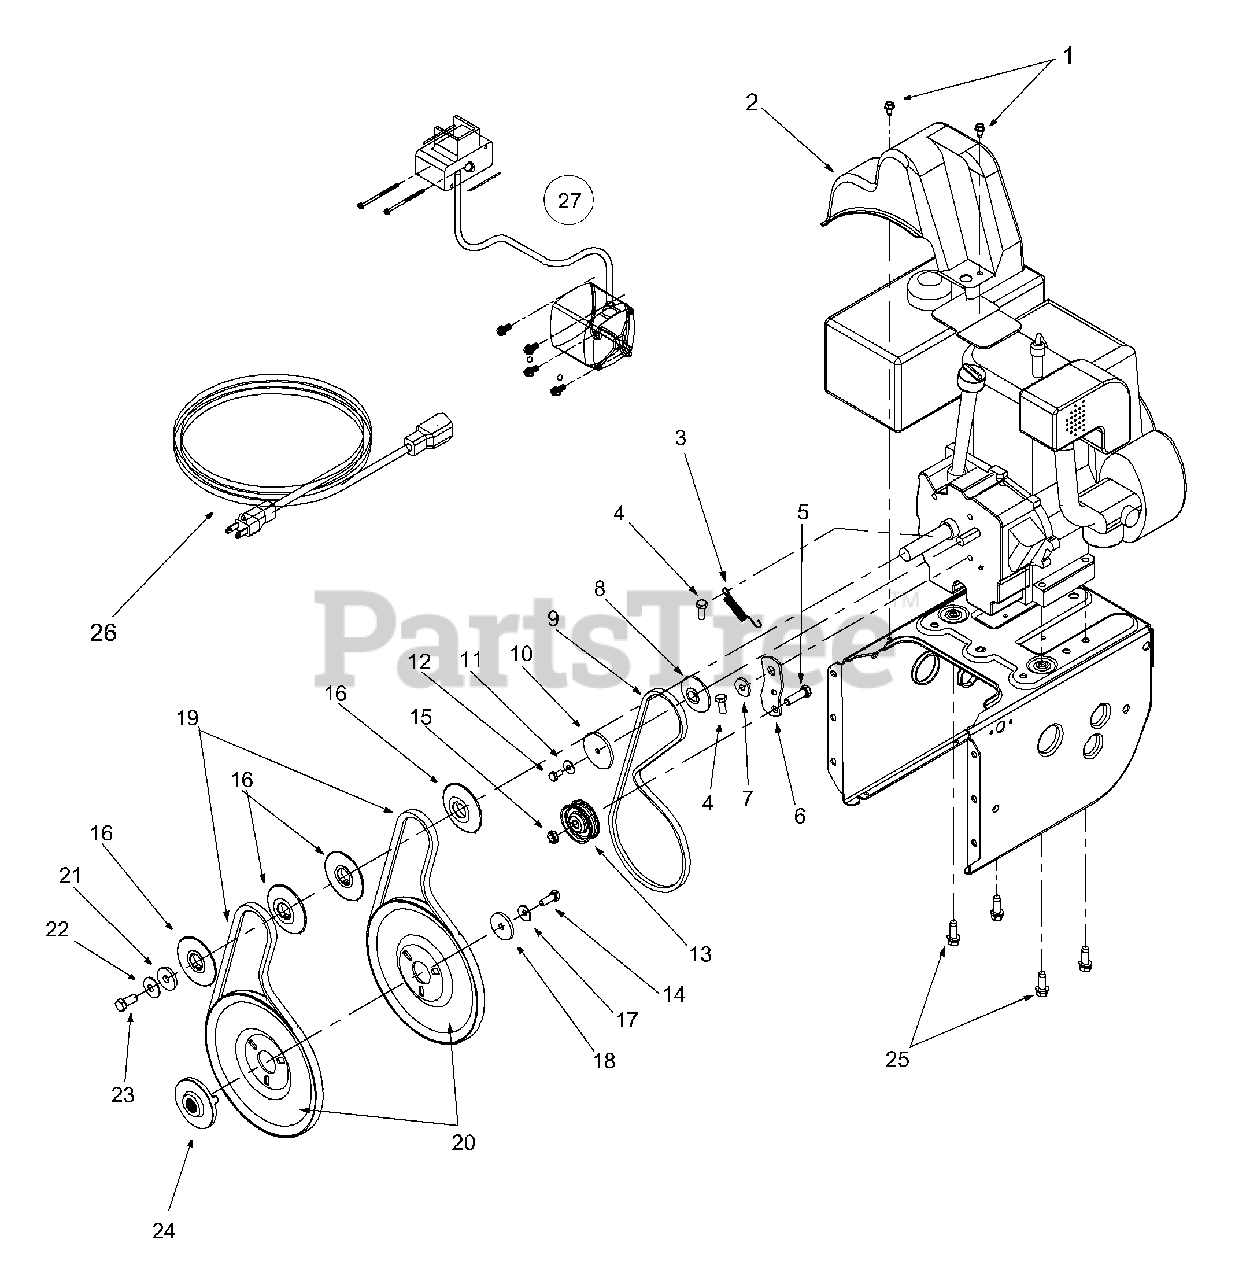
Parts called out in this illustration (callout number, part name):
1	Hex Washer Screw 1/4-20 x .50
2	Belt Cover
3	Extension Spring
4	Hex Screw 5/16-24 x .75
5	Hex Cap Screw 3/8-16 x 1.25
8	Pulley Half
9	V-Belt
10	Pulley Half
11	Bell Washer
12	Hex Cap Screw 1/4-28 x .50
13	Flat Idler
14	Lock Hex Cap Screw 5/16-24
15	Lock Jam Nut 3/8-16
16	Pulley Half
17	Bell Washer
18	Flat Washer
19	Belt
20	Auger Pulley
21	Flat Washer 3/8 x 1.25 OD
22	Bell Washer
23	Hex Cap Screw 3/8-24
24	Adapter Pulley
25	Hex Screw 3/8-16 x 1.0
26	Extension Cord
27	Electric Start Kit
